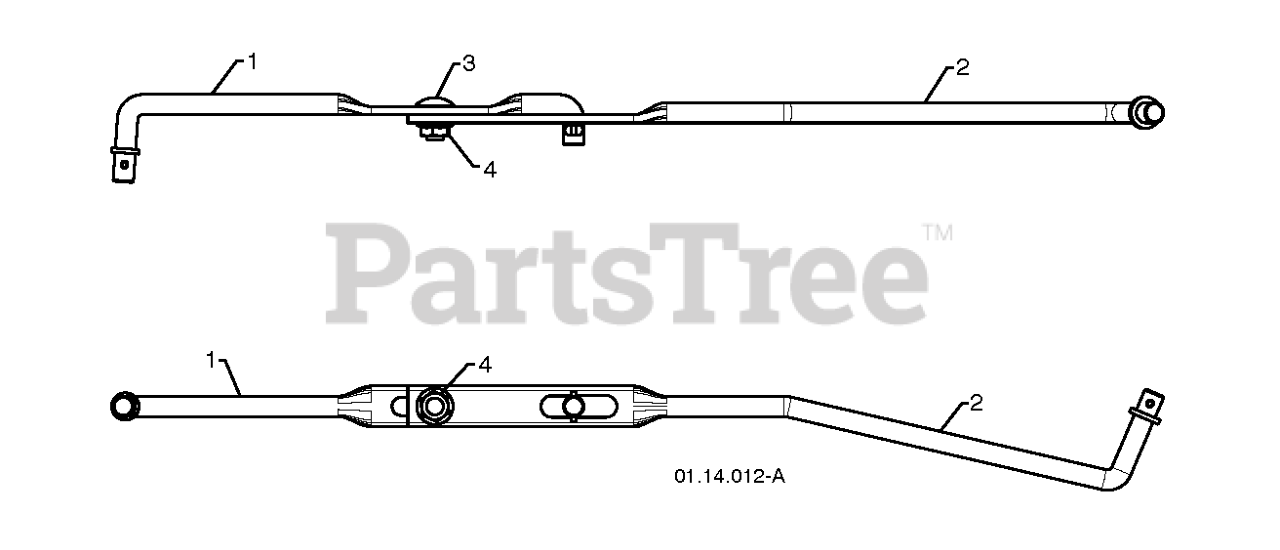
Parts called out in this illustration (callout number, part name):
1	ROD.SHIFTER.TOP.HYD
2	ROD, LOWER, SPEED CONTROL
3	BOLT
4	NUT.FLANGE.5/16
